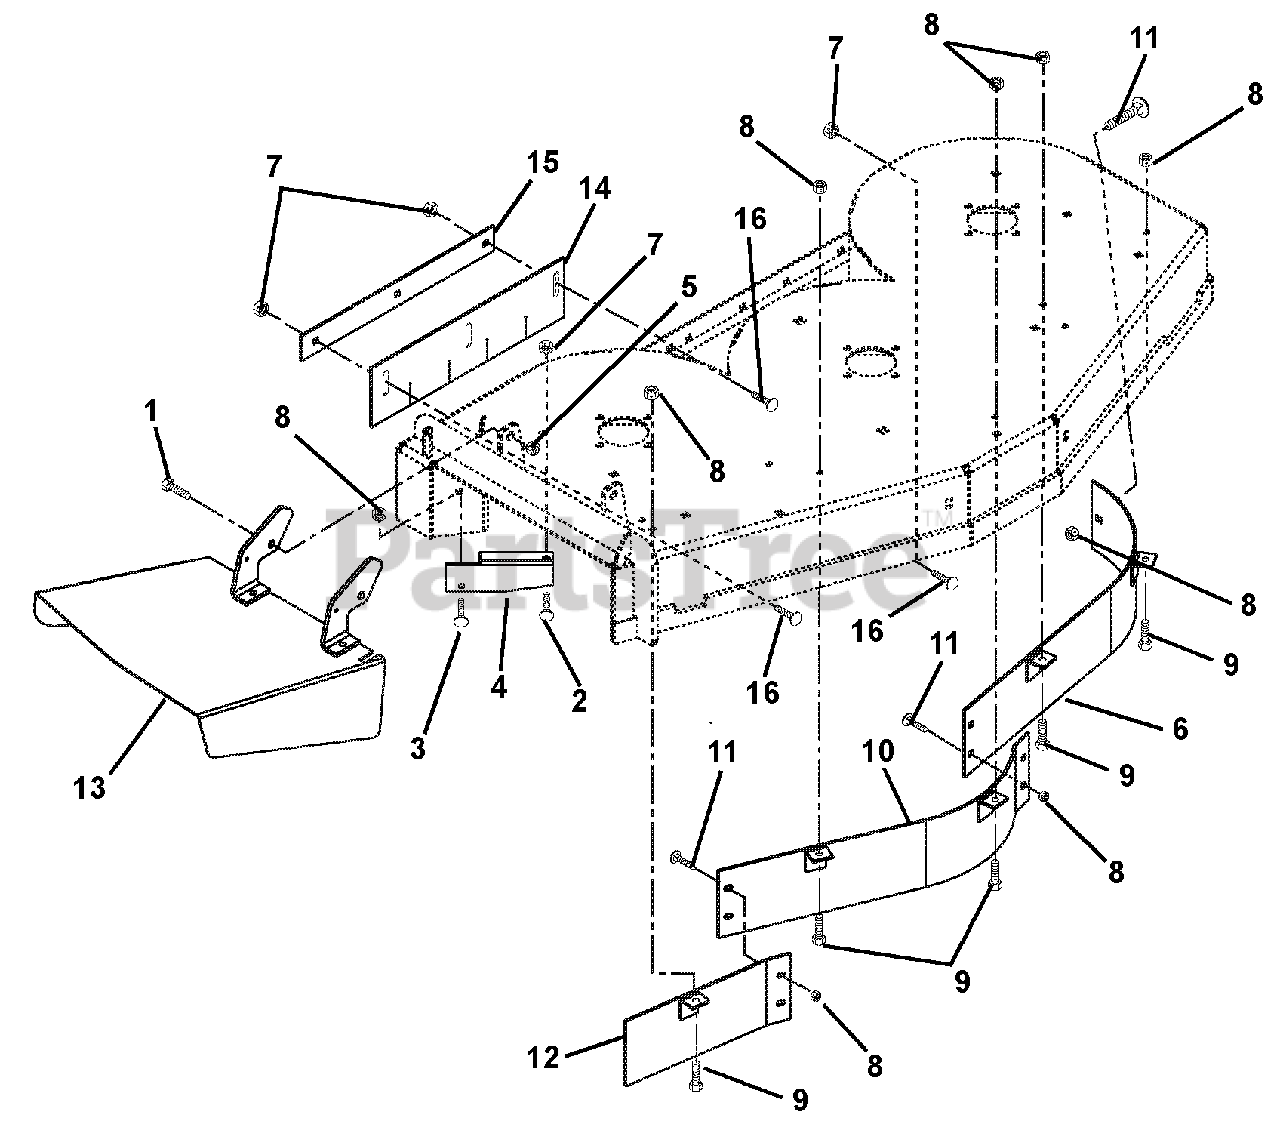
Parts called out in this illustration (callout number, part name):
1	Bolt, Hex .50-13 x 1.25 Grade 5
2	Bolt, Round Head Square Neck .38-16 x .75 Grade 5
3	Bolt, Round Head Square Neck .31-18 x 1.00 Grade 5
4	Deflector 44"/48" (108)
5	Nut, Locking-Nylon .50-13
6	Weldment, Upper Baffle Left (108)
7	Nut, Locking-Top-Flange .38-16
8	Nut, Locking-Top-Flange .31-18
9	Bolt, Hex .31-18 x .75 Grade 5
10	Weldment, Upper Baffle Center (108)
11	Bolt, Round Head Square Neck .31-18 x .75 Grade 5
12	Weldment, Right Hand Baffle-Upper (108)
13	Chute, Discharge
14	Skirt, Rubber
15	Strip, Striper Mount
16	Bolt, Round Head Square Neck .38-16 x 1.00 Grade 5
